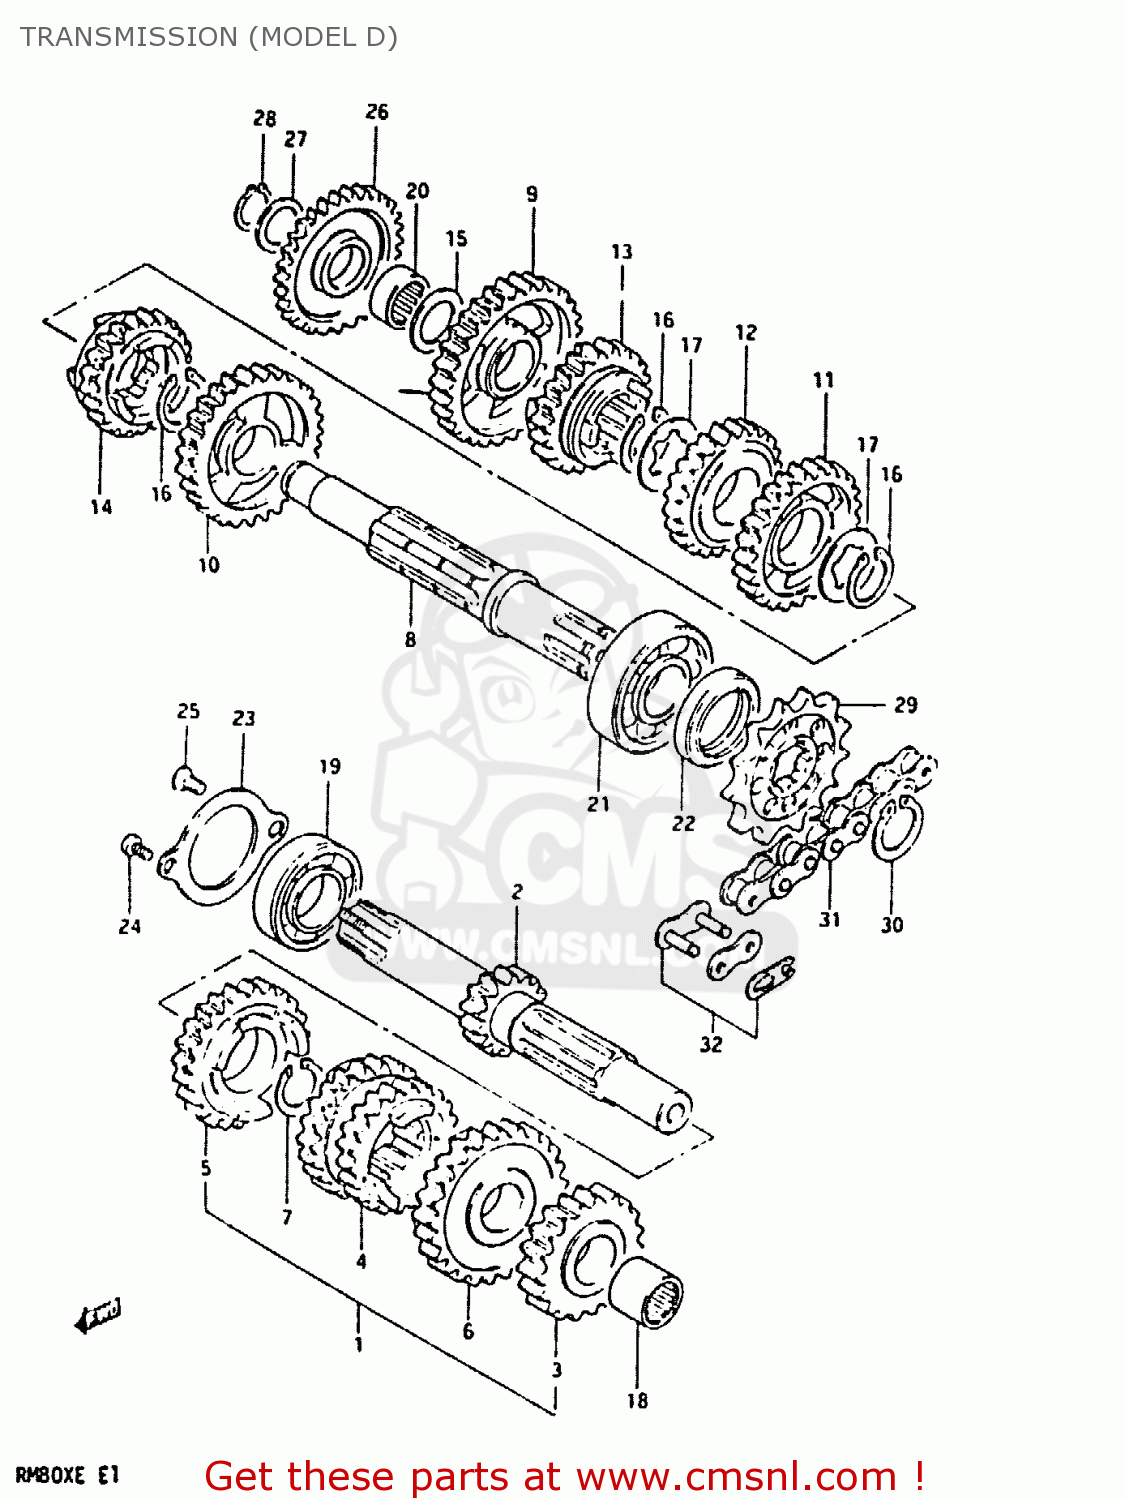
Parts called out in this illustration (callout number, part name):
1	SHAFT,COUNTER
2	SHAFT,COUNTER
3	GEAR,SECOND DRIVE
4	GEAR,THIRD/FOURTH DRIVE
5	GEAR,FIFTH DRIVE
6	GEAR,SIXTH DRIVE
7	CIRCLIP
8	SHAFT,DRIVE
9	GEAR,FIRST DRIVEN
10	GEAR,SECOND DRIVEN
11	GEAR,THIRD DRIVEN
12	GEAR,FOURTH DRIVEN
13	GEAR,FIFTH DRIVEN
14	GEAR,SIXTH DRIVEN
15	WASHER
16	CIRCLIP
17	WASHER,LOCK
18	ROLLER BEARING (13X19X1
19	BEARING
20	BEARING(15X21X12)
21	Bearing
22	OIL SEAL (20X35X5)
23	RETAINER,CNTR SHAFT BEARING
24	SCREW
25	SCREW
26	GEAR,KICK STARTER IDLER(NT:26)
27	THRUST WASHER
28	CIRCLIP
29	SPROCKET,ENGINE
30	CIRCLIP
31	CHAIN ASSEMBLY,DRIVE
32	JOINT,CHAIN
